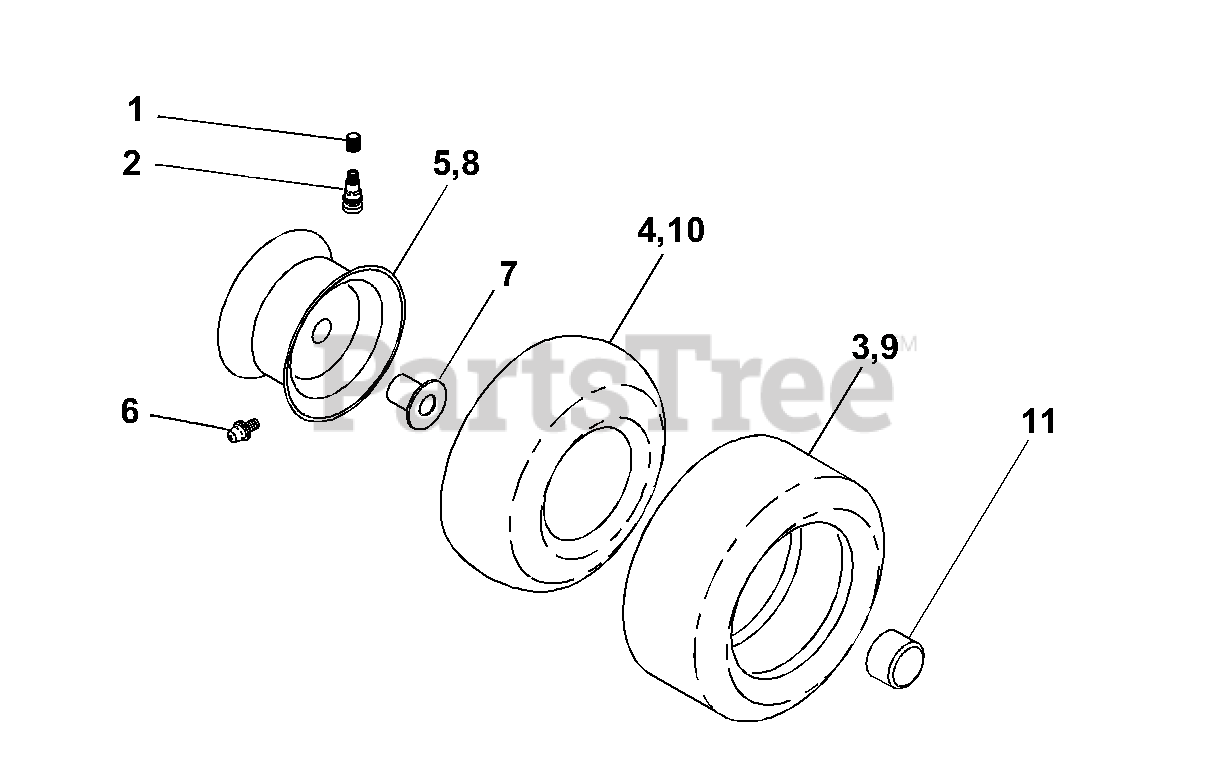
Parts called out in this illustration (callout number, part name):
1	Cap Valve Tire
2	Stem Valve
3	Tire F Ts 15 X 6 0 - 6 Service
4	Tube Front
5	Rim Asm 6" front Silver Service
6	Fitting Grease
7	Bearing Flange
8	Rim Asm 8" rear Silver Service
9	Tire R Ts 20 x 10-8 C Service
10	Tube Rear
11	Cap Axle Blk 1 50 X 1 00
